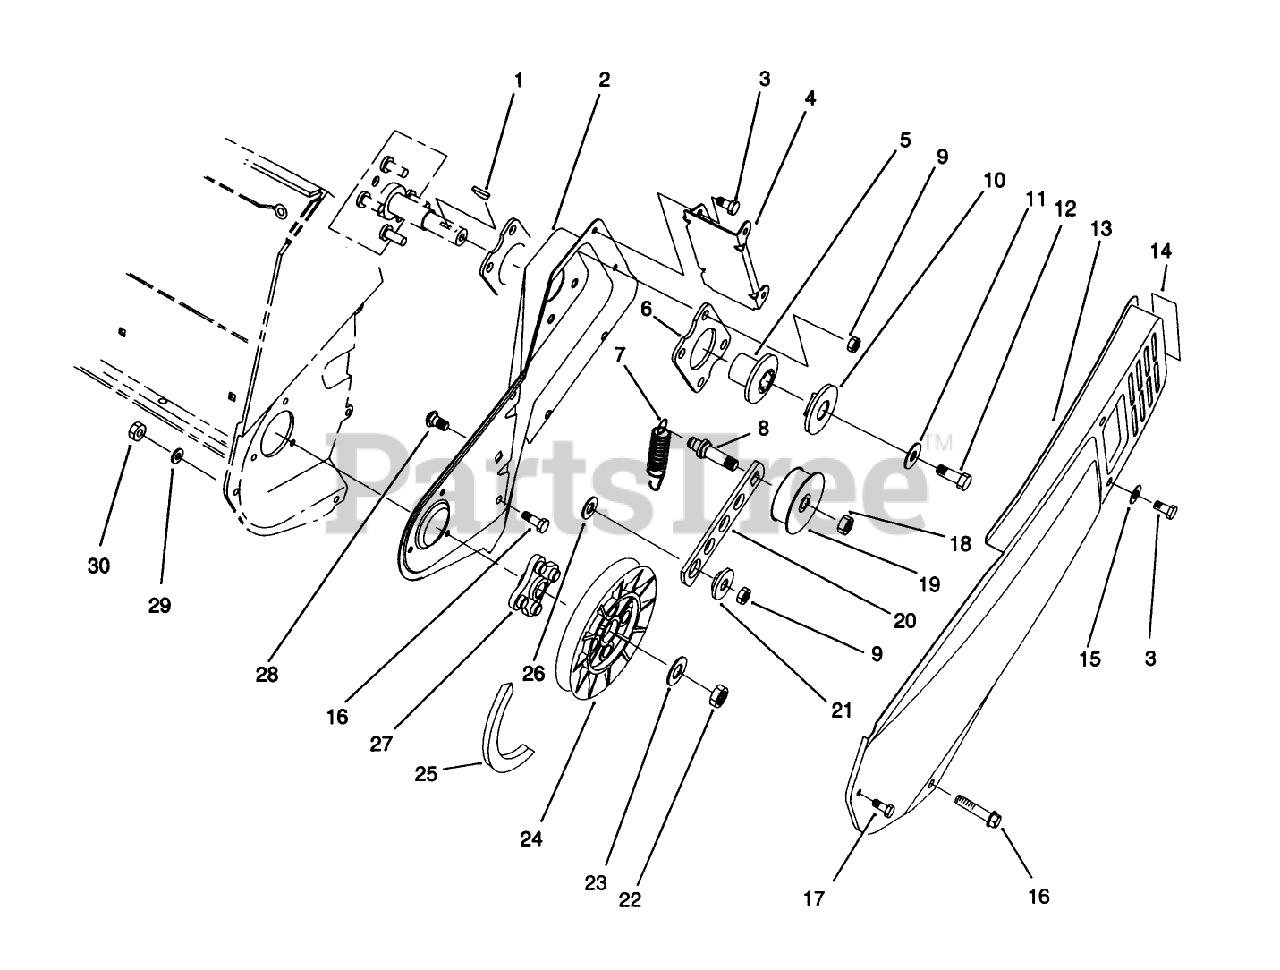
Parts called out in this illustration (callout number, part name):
1	KEY-WOODRUFF
3	SCREW-HWH
5	HUB-HALF SHEAVE
7	SPRING-EXTENSION
8	PIN-IDLER
9	NUT-LOCK, NI
10	CAP-HALF SHEAVE
11	WASHER-FLAT
12	SCREW-HH
15	WASHER-FLAT
16	SCREW-PLASTIC
19	PULLEY-IDLER
20	ARM-IDLER
21	BUSHING-IDLER
22	NUT-LOCK, NI
23	WASHER-FLAT
24	PULLEY-DRIVEN
25	V-BELT
26	WASHER
28	SCREW-CARR
29	WASHER-FLAT
30	NUT-LOCK, NI
